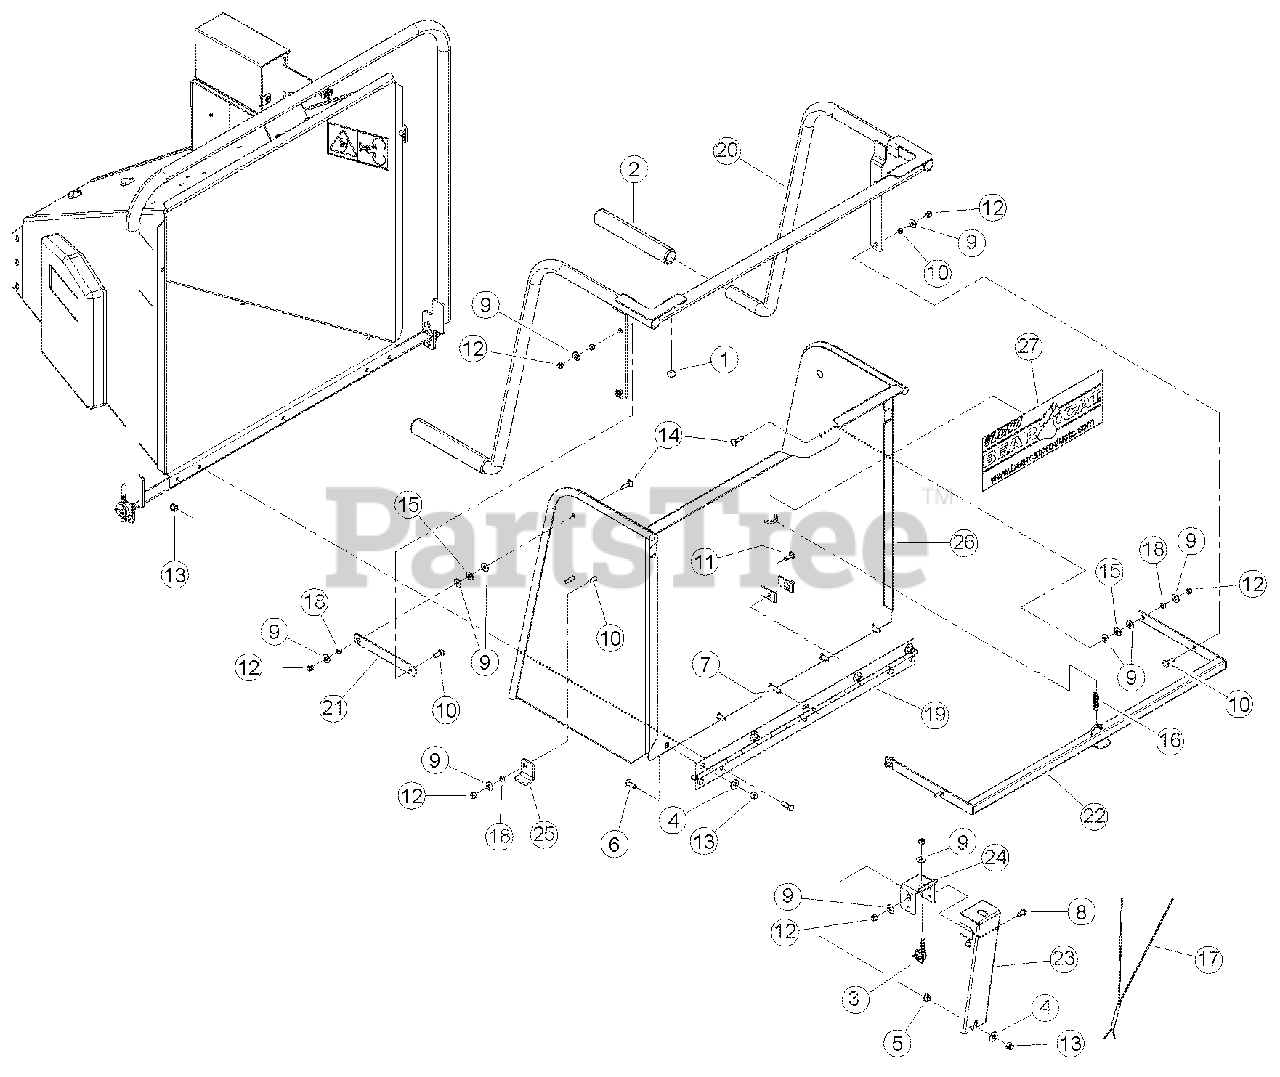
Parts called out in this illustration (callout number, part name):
1	BUMPER, RUBBER
2	GRIP, 1.219 X 10.00
4	WASHER, 3/8 FLAT ZP
5	NUT, 3/8 SERR FLANGE ZP
6	BOLT, 3/8 X 1 CRG GR5 NC ZP
7	BOLT, 3/8 X 1-1/2 CRG GR5 NC ZP
8	SCREW, 11/32 X 7/8 HWH AB THREAD ZP
9	WASHER, 5/16 FLAT ZP
10	BOLT, 5/16 X 1 CRG GR5 ZP
11	BOLT, 5/16 X 7/8 CRG GR5 NC ZP
12	NUT, 5/16 NE NYLOCK ZP
13	NUT, 3/8 NE NYLOCK ZP
14	BOLT, 5/16 X 1-1/4 CRG GR5 ZP
15	WASHER, 5/16 ID. X 7/8 OD. NYLON FLAT
16	SPRING 1/2 X 2.00 LG,ZP
17	HARNESS, SAFETY BAR
18	SPACER, IDLER PIVOT
19	HINGE, EXTENSION TRAY
20	WELDMENT, KNEEBAR
21	LINK, PARALLEL
22	WELDMENT, KNEEBAR PIVOT
23	SHIELD, KNEEBAR SWITCH
24	BRACKET, SWITCH
25	LOCK, SAFETY BAR
26	ASSEMBLY, EXTENSION TRAY, SERVICE PART
27	DECAL, BEARCAT WEB
